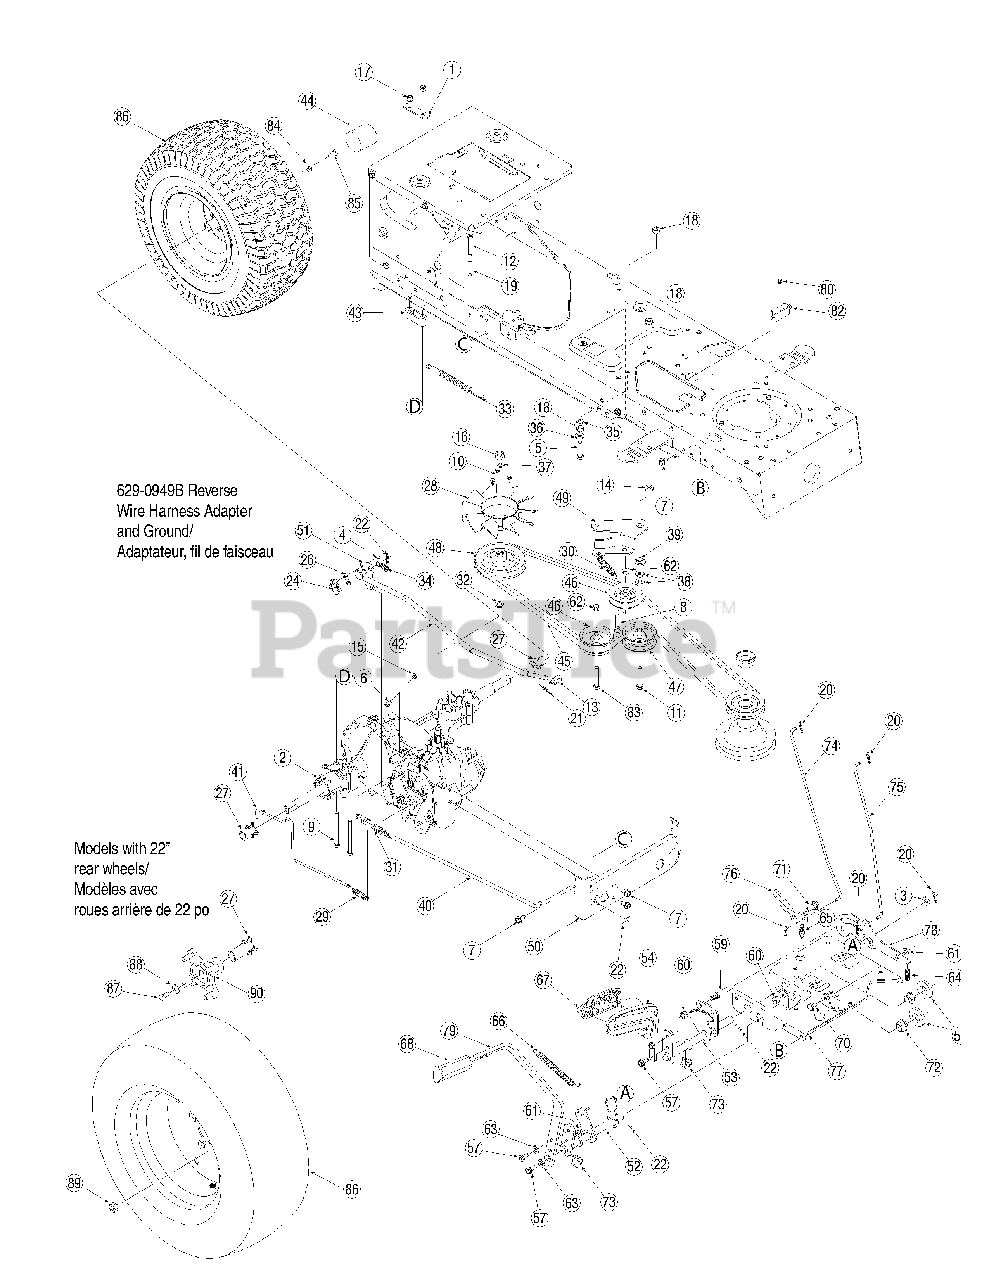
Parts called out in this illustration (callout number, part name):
1	Transaxle Mtg. Brkt.
2	Hydrostatic Transmission (SLT Models)
3	Flat Washer .385 x .870 x .092
4	Hex Wash HD AB S-Tapp Scr #8-.50
5	Hex Screw 3/8-16 x 1.50
6	Hex Wash HD Tapp Scr 1/4-20 x .375
7	Hex Wash HD AB Tap Scr 5/16-12 x .75
8	Hex Washer Scr 3/8-16 x 1.25
9	Hex Bolt 5/16-18 x 3.5" Lg.
10	Hex Tap Scr #12 x .375
11	Hex Bolt 3/8-16 x 2.25" Lg.
12	Hex Wash HD Bolt 1/4-20 x 1.50" Lg.
13	Adjustment Ferrule 3/8-24
14	Flat Washer .385 ID X 1.0 OD X .130
15	Hex Cent-L Nut 1/4-20
16	Hex Nut 1/2-20 Grade 5
17	Flange Locknut 5/16-18 Gr. F, Ny lon
18	Hex. Flanged L-Nut 3/8-16 Gr. F
19	Spacer .260 x .375 x 1.030 Lg.
20	Cotter Pin .072 Dia. x 1.13
21	Cotter Pin 3/32 x .75
22	Cotter Pin 3/32 dia x 1.00 Lg.
24	Short Spring Switch
26	Insulator Nut Plate
27	Sleeve 0.765 x 1.5" Lg.
27	Sleeve 0.765 x 2.410" Lg.
29	Extension Spring .47 OD x 2.03 Lg.
30	Extension Spring
31	Ext. Spring .59 OD x 4.00 Lg.
33	Extension Spring .75 x 5.39
34	Extension Spring 3/8 x 1.44
35	L-Wash 3/8 ID
36	Flat Washer .385 ID x .87 OD x .06
37	L-Washer 1/2" ID
38	Flat Washer .406 ID x .812 OD x .134
39	Shoulder Spacer
41	Hydrostatic By pass Rod
42	Hydrostatic Control Rod
43	Transaxle Spacer
46	Pulley, V-Type Drive 3.06
47	Idler Pulley, Flat 2.75 OD
48	In put Pulley
50	Transmission Torque Bracket
51	Switch Ac tu a tor Bracket
52	Brake Control Assembly
53	Drive Control Assembly
54	Hydro Pedal Assembly
56	Flat Washer .640 ID x 1.24 OD x .06
57	Hex Wash. Hd. Scr. 5/16-18 x .75 Lg.
59	Pin 3/8-16 x 2.68 Lg.
60	Flange Lock-Nut 3/8-16 Gr. F Ny lon
61	Hex Flange L-Nut 5/16-18
62	Hex Jam Nut 7/16-20
63	L-Wash 5/16 ID
64	Compression Spring
65	Extension Spring, .50 OD x 1.41
66	Extension Spring, .50 Dia. x 6.37
67	AutoDrive Pedal Pad
70	Shld. Scr .437 Dia x .162 Lg.
71	Shoulder Screw .500 x .25
72	Hex Flange Bearing .630 ID
73	Hex Flanged Bearing .628 ID
74	Brake Lock Rod
75	Cruise Control Rod
76	Cruise Control Latch
77	Steering Support Bracket
78	Drive Lock out Bracket
80	Shoulder Scr #10-32 x .50" Lg.
82	Inter lock Switch
83	Hex L-Wash HD Scr 3/8-16 x 1.5
84	Cupped Washer .345 ID x .88 OD x .060
85	Hex L-Bolt 5/16-24 x .75 Gr. 5
86	Wheel Assembly
87	Hex Hd. Cap Scr. 5/16-24 x .75 Gr. 5
88	Cupped Washer .340 x .872 x .060
89	Lug Nut 7/16-14
90	Wheel Hub Ass'y
